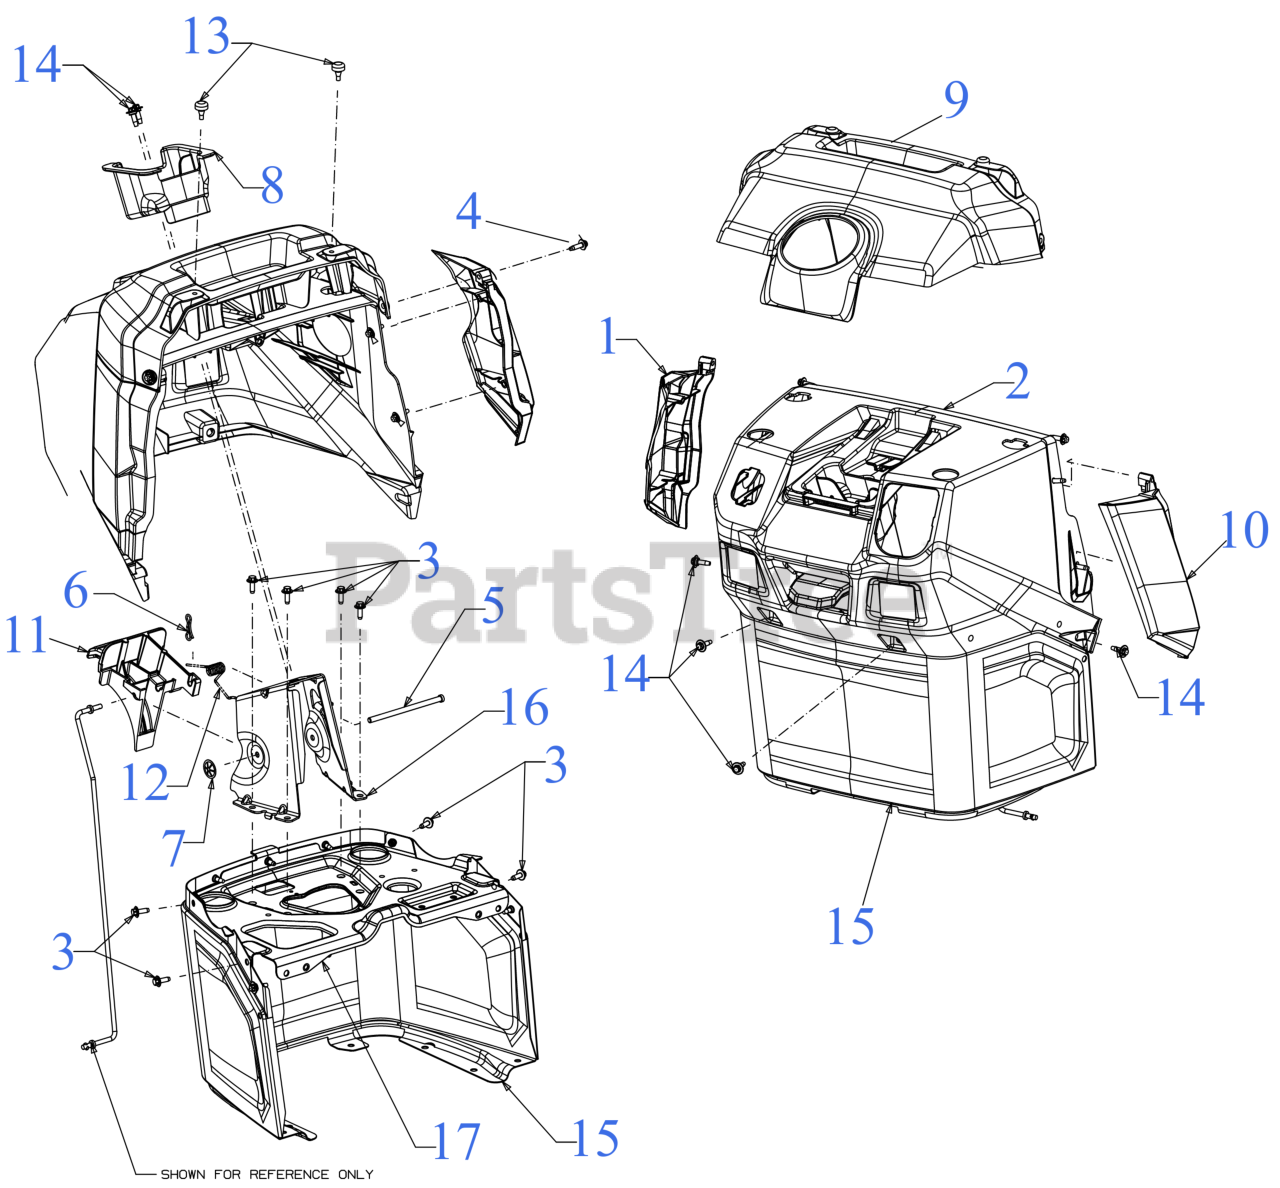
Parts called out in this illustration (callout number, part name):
1	DASH CAP (LH)
2	DASH (UPPER)
3	SCREW M6-1 x .625
4	SCREW 1/4-10 x .750
5	HINGE PIN .25 x 4.50
6	BOW TIE COTTER PIN 1/4-5/16
7	PUSH ON NUT
8	STEERING SHAFT BEARING
9	UPPER DASH CAP (CRAFTSMAN)
10	DASH SIDE CAP (RH)
11	BRAKE LEVER
12	TORSION SPRING .330 ID
13	BUMPER, .62 DIA x .3
14	SHOULDER SCREW M6-1 .368 X.115
17	DASH PLATE
